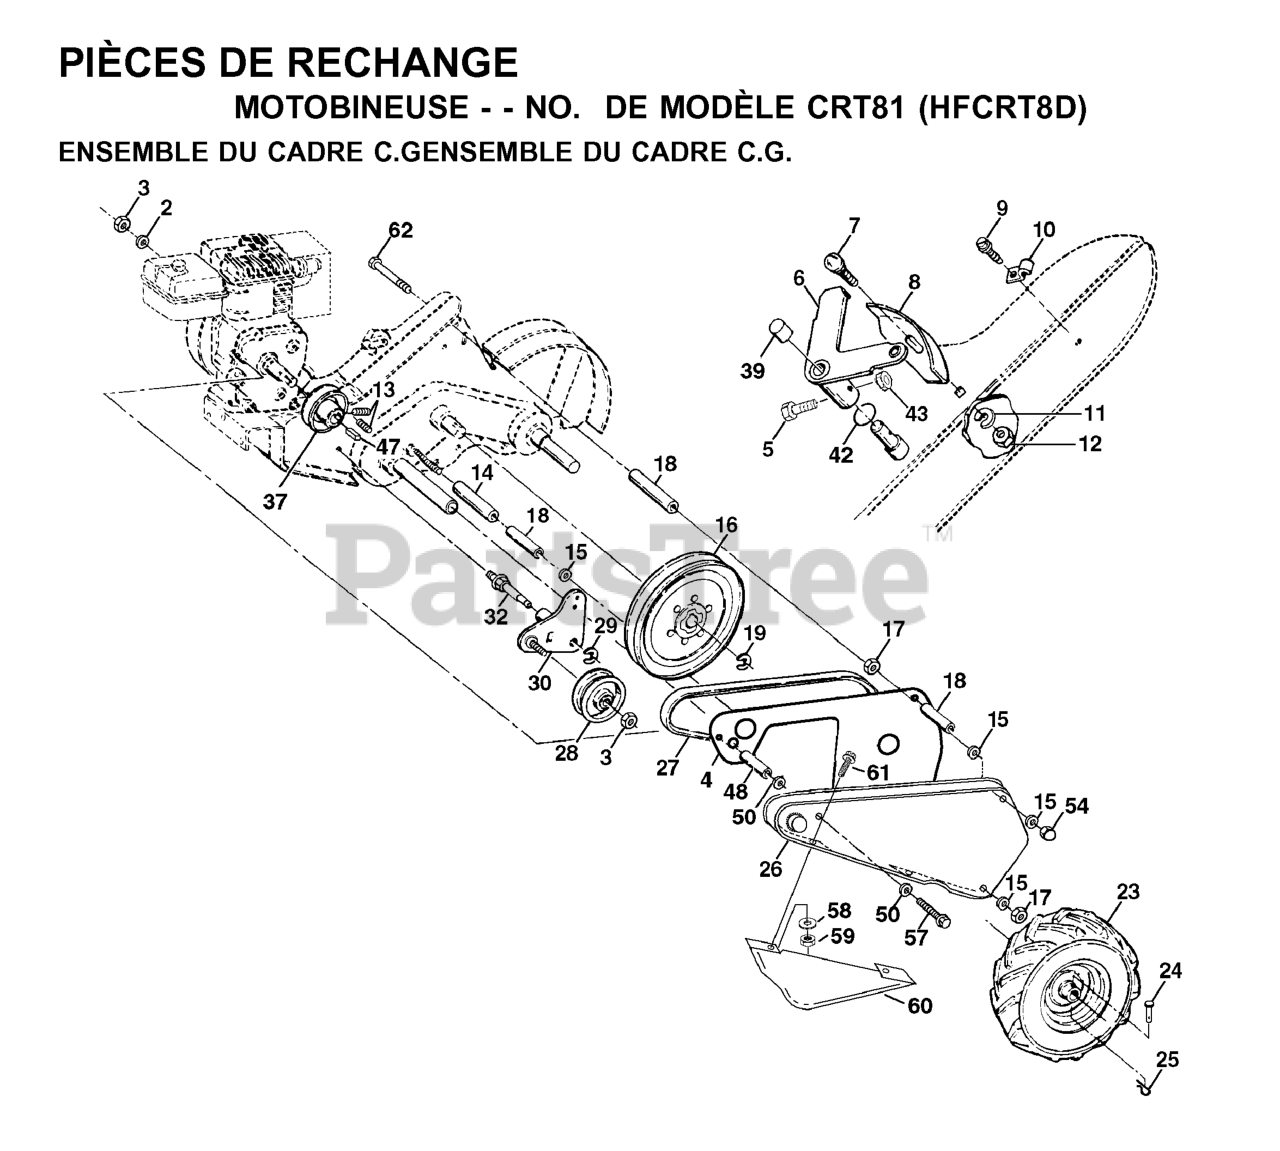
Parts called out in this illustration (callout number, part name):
2	WASHER, LOCK 3/8
3	NUT.HEX.3/8-16UNC
5	SCREW, SHIFT LEVER
6	LEVER ASM CRT
8	PANEL.INDICATOR.SHIFT.BLACK
9	SCREW.HEX.WSH.SLT.#10-24X.50
10	CONDUIT.CLIP.PLATED
11	LOCKWASHER
12	NUT
14	SPACER-SPLIT.327 X .42
15	WASHER
16	SHEAVE, TRANSMISSION
18	SPACER SPLIT
19	RETAINING RING LT
23	TIRE.16X4-8.CHEVRON.TILLER
25	SPRING TI
27	BELT, DRIVE
28	PULLEY-IDLER TI
30	BRACKET.ASM.IDLER.BLACK
32	SHAFT, IDLER ARM
37	SHEAVE, ENGINE
39	CAP.PLUNGER.BLACK
47	KEY, SQUARE
50	WASHER
57	Bolt, Hex Head 1/2-20 x 2-3/4
58	WASHER, .196 X .625 X 16 GA
59	NUT **
61	SCREW.PNHD.10-24
62	BOLT 5/16-18X4 1/2
532124366	RIM
532124718	VALVE STEM LT
